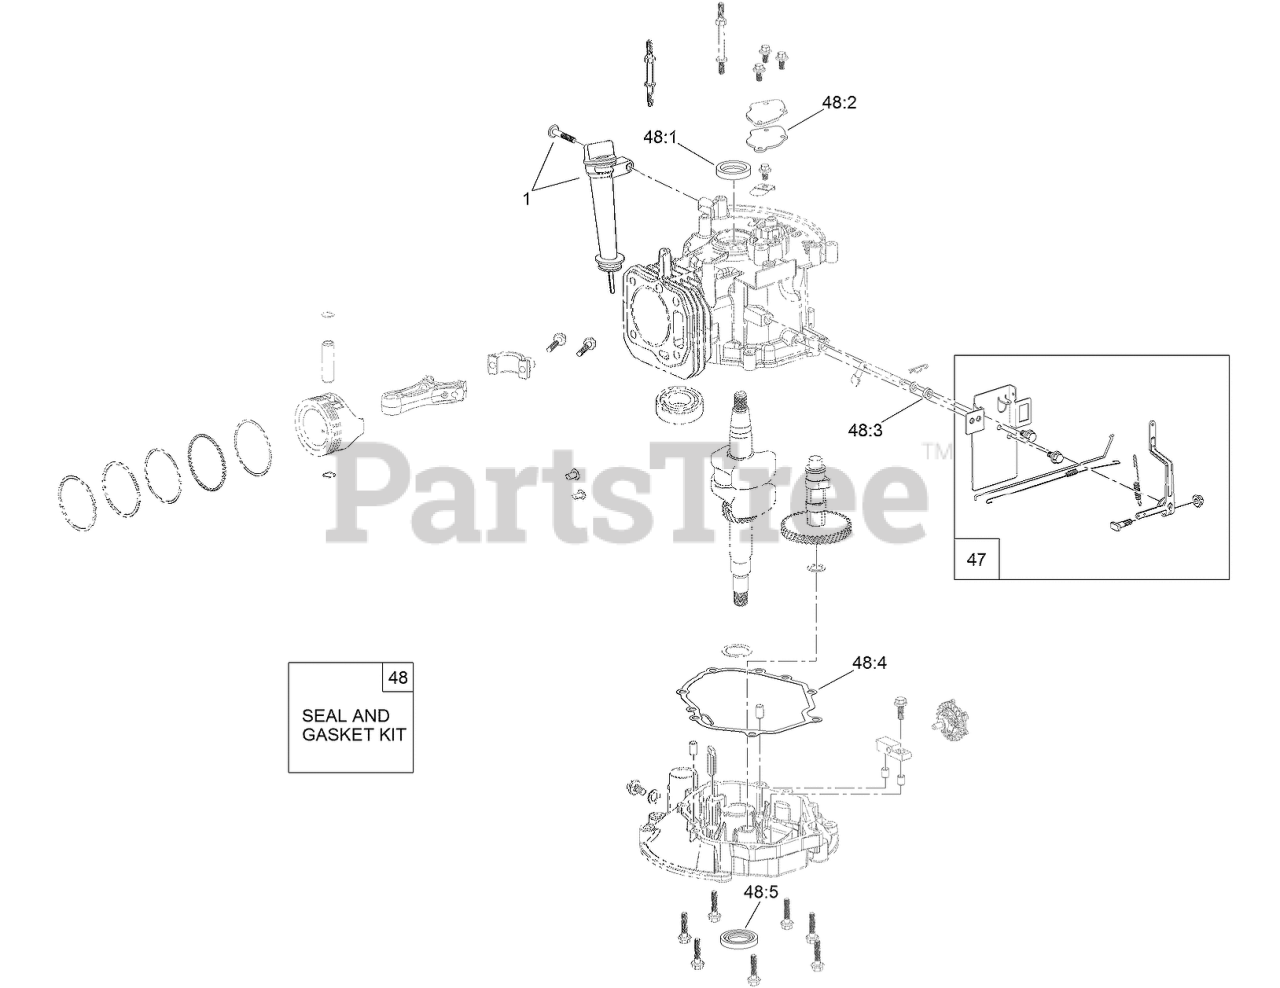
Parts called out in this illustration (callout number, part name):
1	DIPSTICK AND FILL TUBE KIT
47	GOVERNOR ARM KIT
48	SEAL AND GASKET KIT
48:1	SEAL-OIL
48:2	GASKET-BREATHER
48:3	SEAL-OIL
48:4	GASKET-COVER, CASE
48:5	SEAL-OIL
